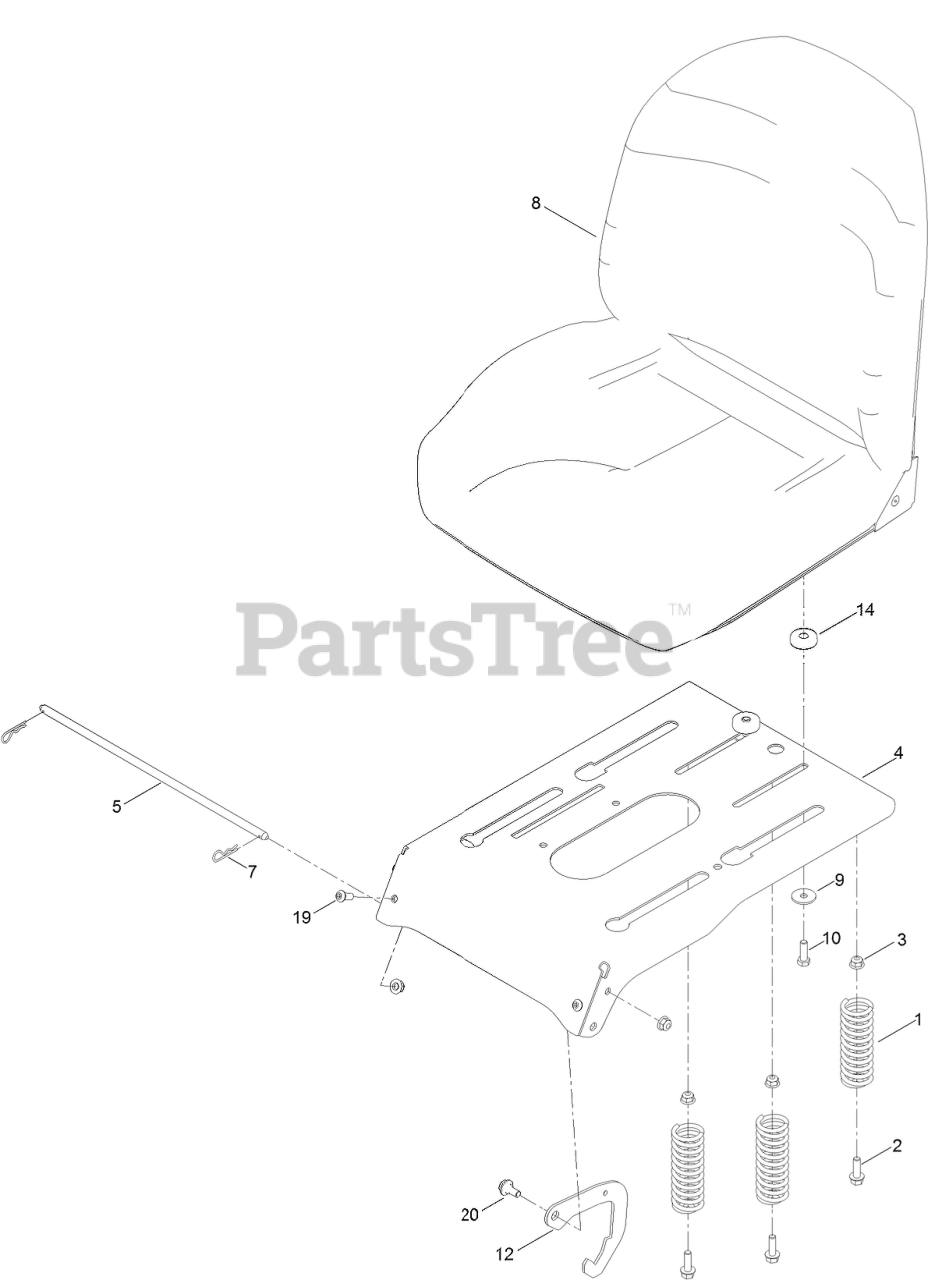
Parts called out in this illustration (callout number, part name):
1	SPRING-COMPRESSION
2	SCREW-HHF
3	NUT-HF, NI
4	PAN-SEAT, DELUXE
5	ROD-PIVOT, NARROW
7	PIN-COTTER
9	WASHER-PIVOT
10	SCREW-HH
12	LATCH-SEAT
14	BUSHING-SLIDE, SEAT
19	SCREW-HSBH
20	SCREW-SHOULDER
